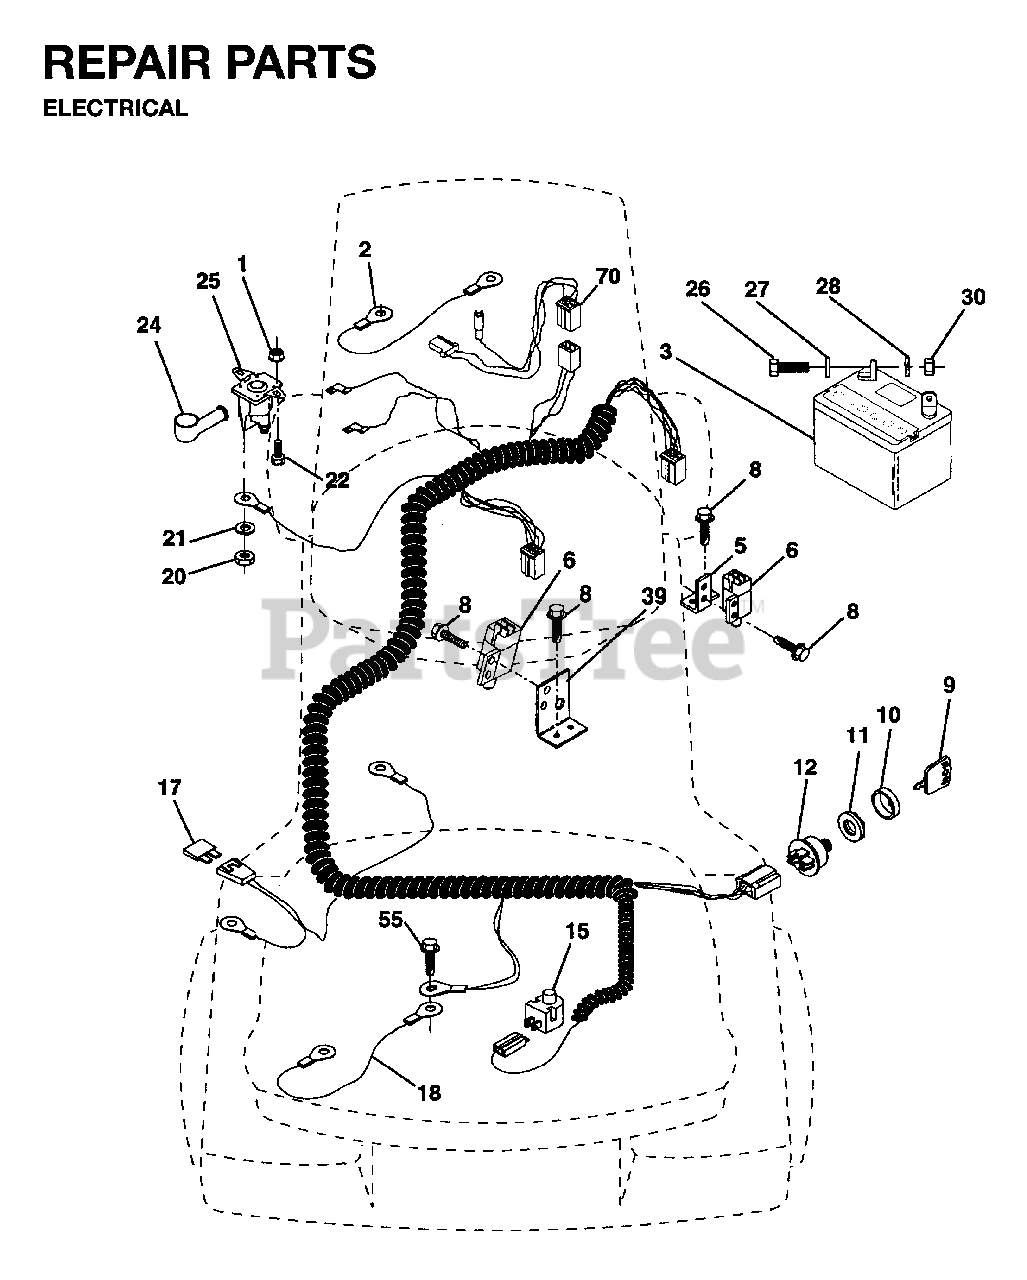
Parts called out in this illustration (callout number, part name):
1	NUT.CROWNLOCK.1/4
2	CABLE ASM
5	BRACKET LT
6	SWITCH INTERLOCKT
9	KEY-STEEL DELTA
10	COVER SWITCH KEY
11	NUT, IGNITION
12	IGNITION SWITCH
15	SWITCH SEAT
20	NUT
21	LOCKWASHER
22	BOLT
24	TERMINAL COVER
28	LOCKWASHER
30	NUT
36	LOCKWASHER
70	HARNESS, ENGINE
